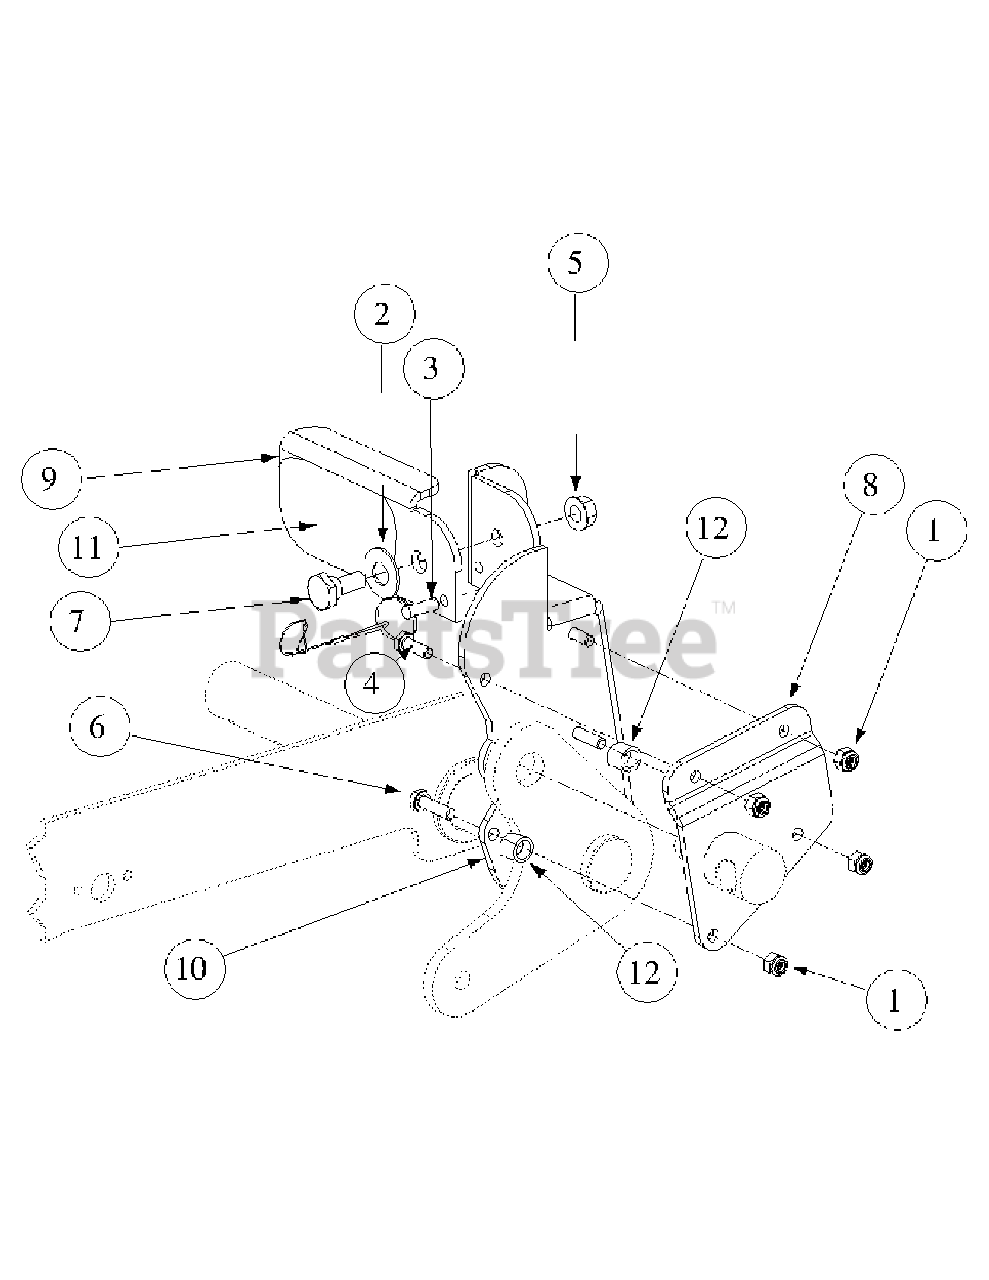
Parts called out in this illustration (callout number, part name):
1	Lock Nut, Nylon Insert, 1/4-20
2	Washer, 1/2 x 1 Shim
3	Detent Pin w/12" Lanyard
4	Hex Cap Screw, 1/4-20, .75
5	Hex Nut, Flange Lock 3/8-16
6	Hex Cap Screw, 1/4-20, 1.00
7	Shoulder Screw, .50 x .27 Lg., 3/8-16
8	Foot Lift Backup Pedal
9	Deck Foot Pedal Lift
10	Deck Foot Pedal Lift
11	Deck Foot Lift Pad
12	Turnbuckle Sleeve
